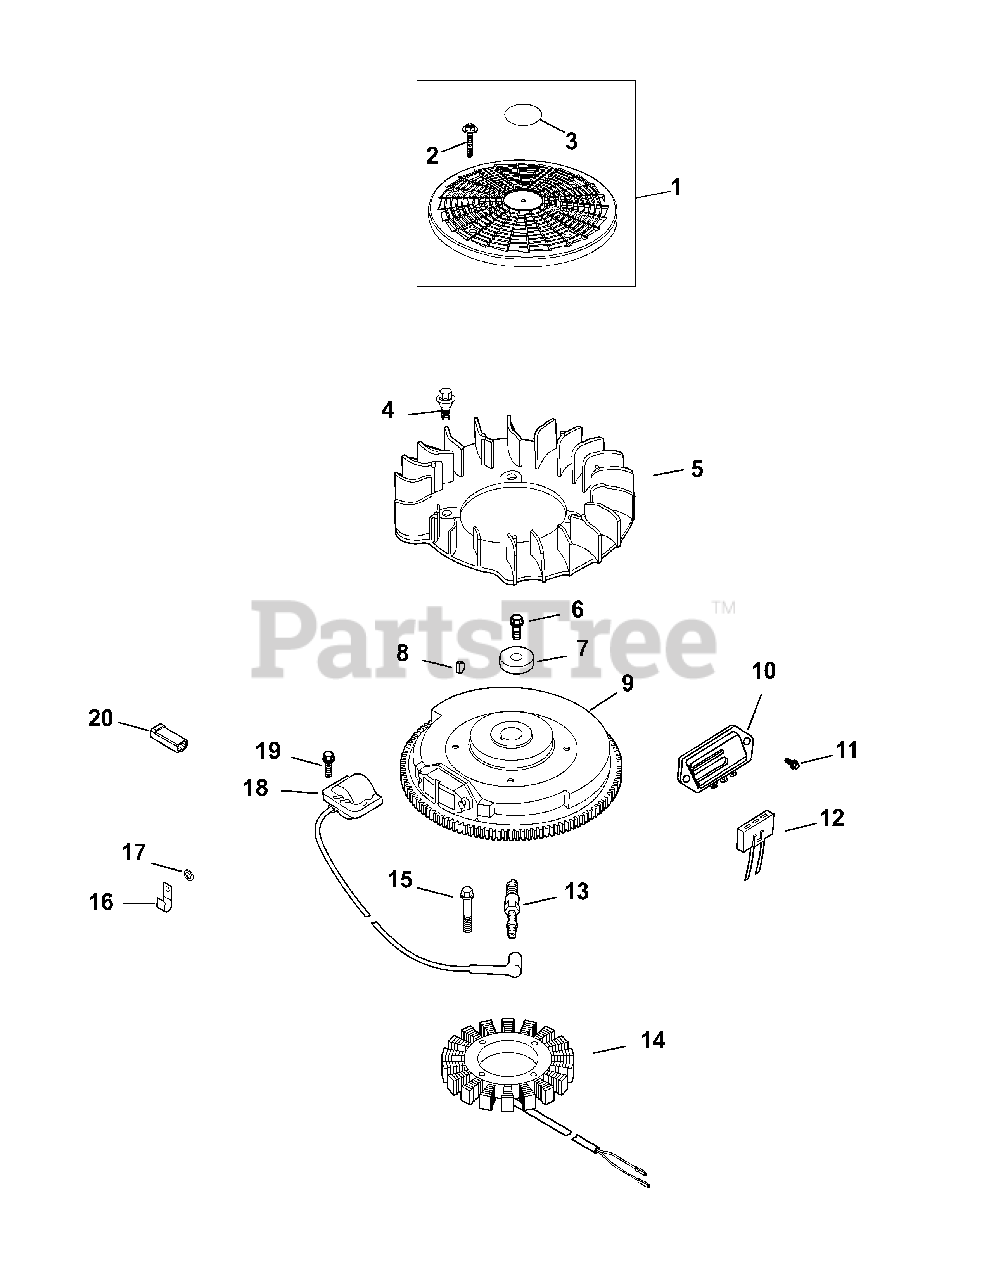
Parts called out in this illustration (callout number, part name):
1	Kit, Grass Screen (Includes 2, 3)
2	Screw, Flg Sems M4 x 0.7 x 25
3	Decal, Grass Screen
4	Bolt, Shoulder
6	Screw, FLG M10X1.5X45
7	Washer, Flat 13/32"
8	Key, 3/16" x 5/8"
10	Rectifier-Regulator
11	Screw, Hex Flange Hi-Lo
12	Connector (3 Contact)
13	Plug, Spark
14	Kit, 15 Amp Stator (Includes KH-25 452 01-S)
15	Screw, THD FRM M5 x 0.8 x 25
16	Clip, Cable
17	Washer, Flat, 1/4"
18	Kit, Module, Ignition (CDI Fixed)
19	Screw, FLG THD FRM M5 x 0.8 x 20
20	Connector (1 Contact)
